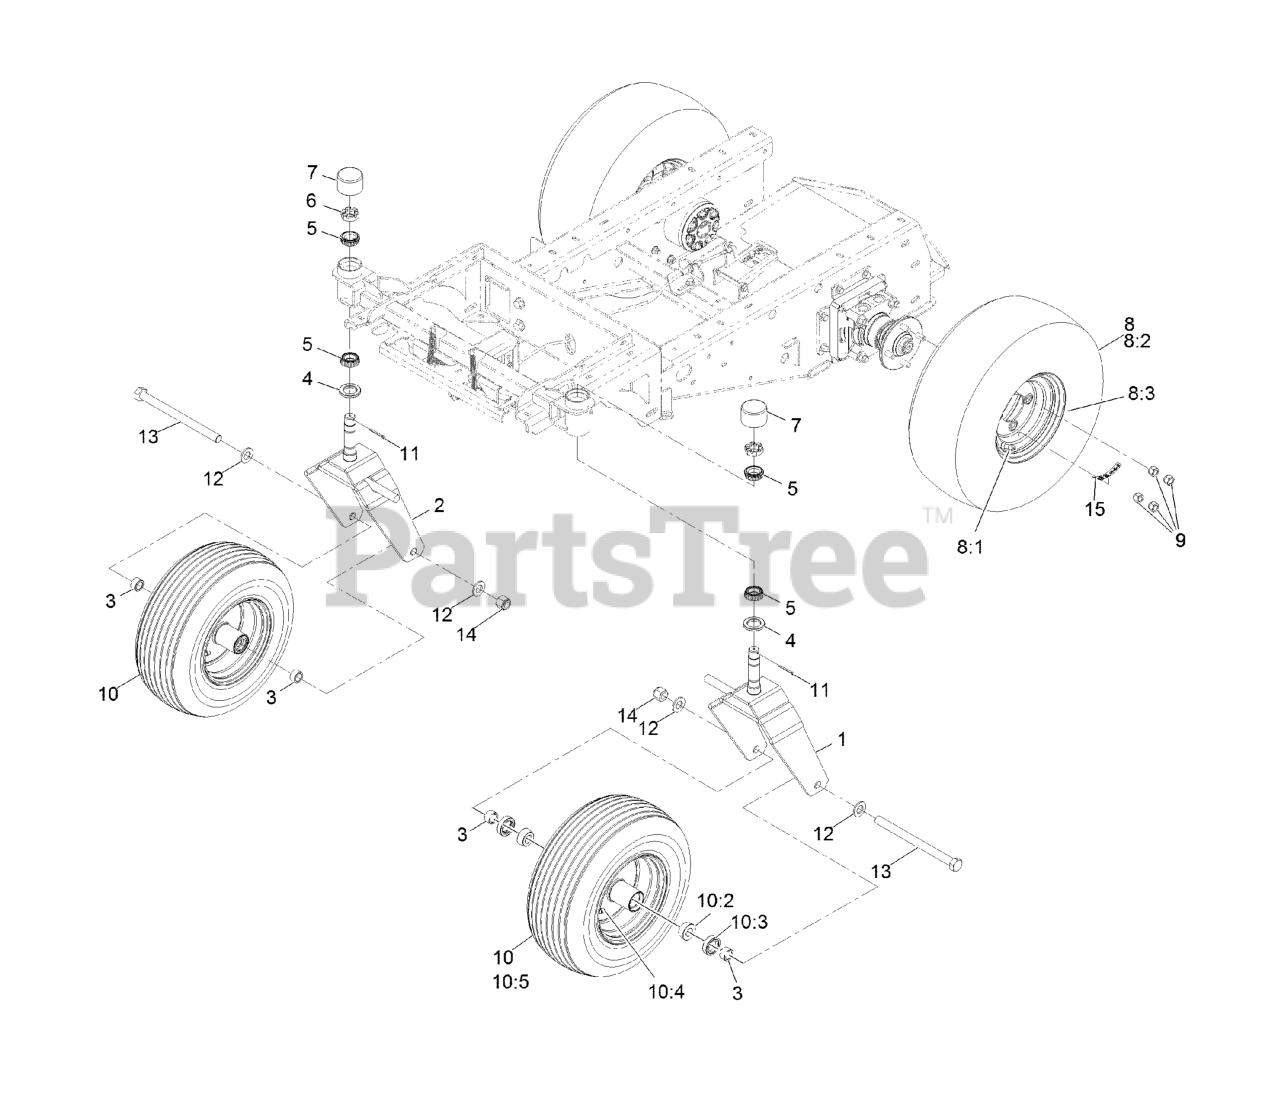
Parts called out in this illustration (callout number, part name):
1	Caster-Lt [black]
2	Caster-Rt [black]
3	SPACER-AXLE
4	SEAL-GREASE
5	CONE-BEARING, OUTER
6	NUT-SHH
7	CAP-DUST, RUBBER
8	WHEEL AND TIRE ASM
8:1	Rim-8 X 5.38, Black
8:2	Tire- 20 X 8 4 Ply
8:3	Stem-Valve
9	NUT-LUG
10	WHEEL AND TIRE
10:2	BEARING-CONE, TAPERED ROLLER
10:3	SEAL-CASTER
10:4	VALVE
10:5	Tire-Rib
11	Pin-Cotter
12	WASHER-FLAT
13	SCREW-HH
14	NUT-LOCK, NI
15	DECAL-TORQUE, WHEEL HUB LUG
